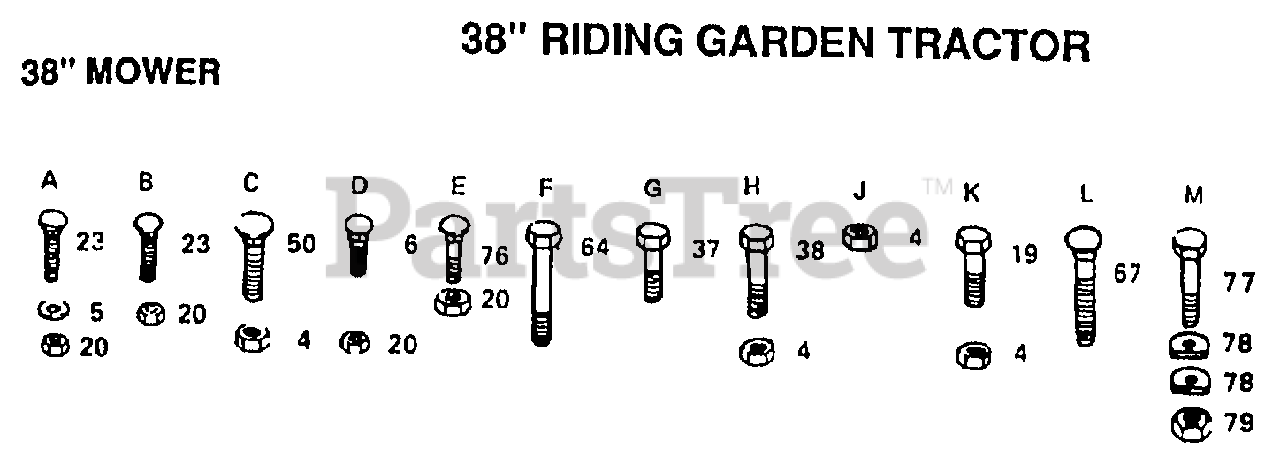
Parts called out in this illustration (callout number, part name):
5	WASHER M
6	BOLT
23	BOLT
37	SCREW
38	SCREW
50	BOLT
64	BOLT
67	BOLT.3/8-14X1.25
77	BOLT LT
78	WASHER T
